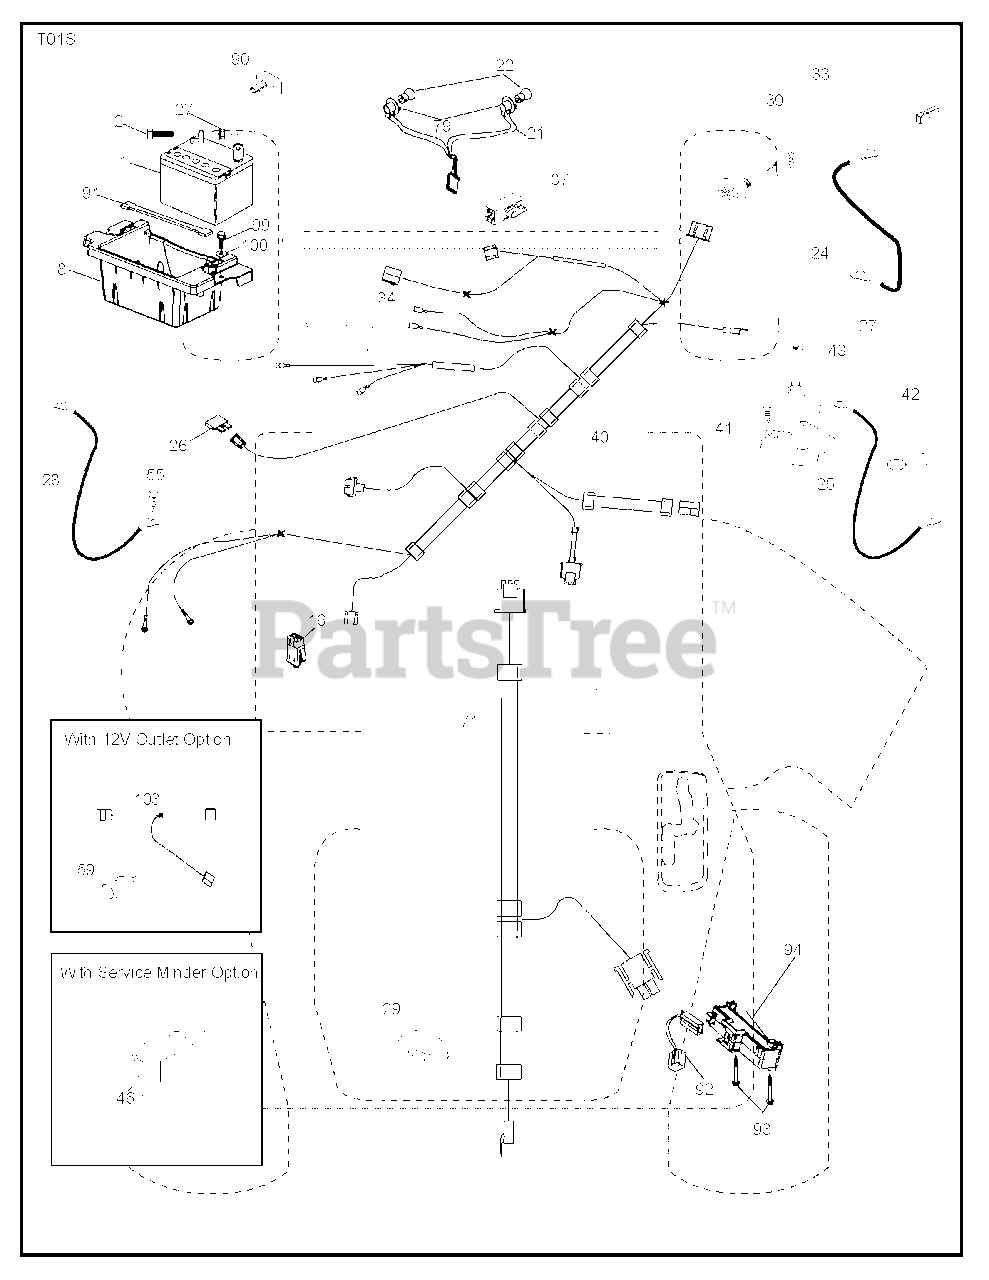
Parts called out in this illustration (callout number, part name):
1	Battery, Dry 30 Amp
2	BOLT.HEX.1/4.X.3/4.DICHROMATE
8	TRAY.ASM.BATTERY.FRT.TEX.CARB
16	SWITCH INTERLOOK PUSH-IN
21	HARNESS.LIGHT W/4152J BULBS
24	CABLE.BATT.POS.WIRE.TG.DA SOL
25	CABLE.STARTER.8GA.17.5
26	FUSE 20AMP
27	NUT
28	CABLE GROUND 6 GA 21" 90T BLK
29	SWITCH.SEAT.DELTA.OPC.
30	SWITCH.IGN.DELTA.W.LGH.ROS
33	KEY.CHAIN.BLISTER.PACK.GEN.USA
40	HARNESS IGN. DASH
41	SCREW
42	TERMINAL COVER
43	SOLENOID.W/BRASS.PLUNGER
55	SCREW 5/16"
71	HARNESS-CHASSIS SUB
79	BULB HOLDER ASM.
87	SWITCH.INTRLCK.CLUTCH.
90	COVER.TERMINAL.BATTERY
91	STRAP.BATTERY.MOUNT.FRONT(2 2)
92	HARNESS.PIGTAIL.CONSLE
93	SCREW.PLASTITE
94	MODULE.REVERSE.ROS
99	SCREW HEXWSHR 1/4-20X3/4
